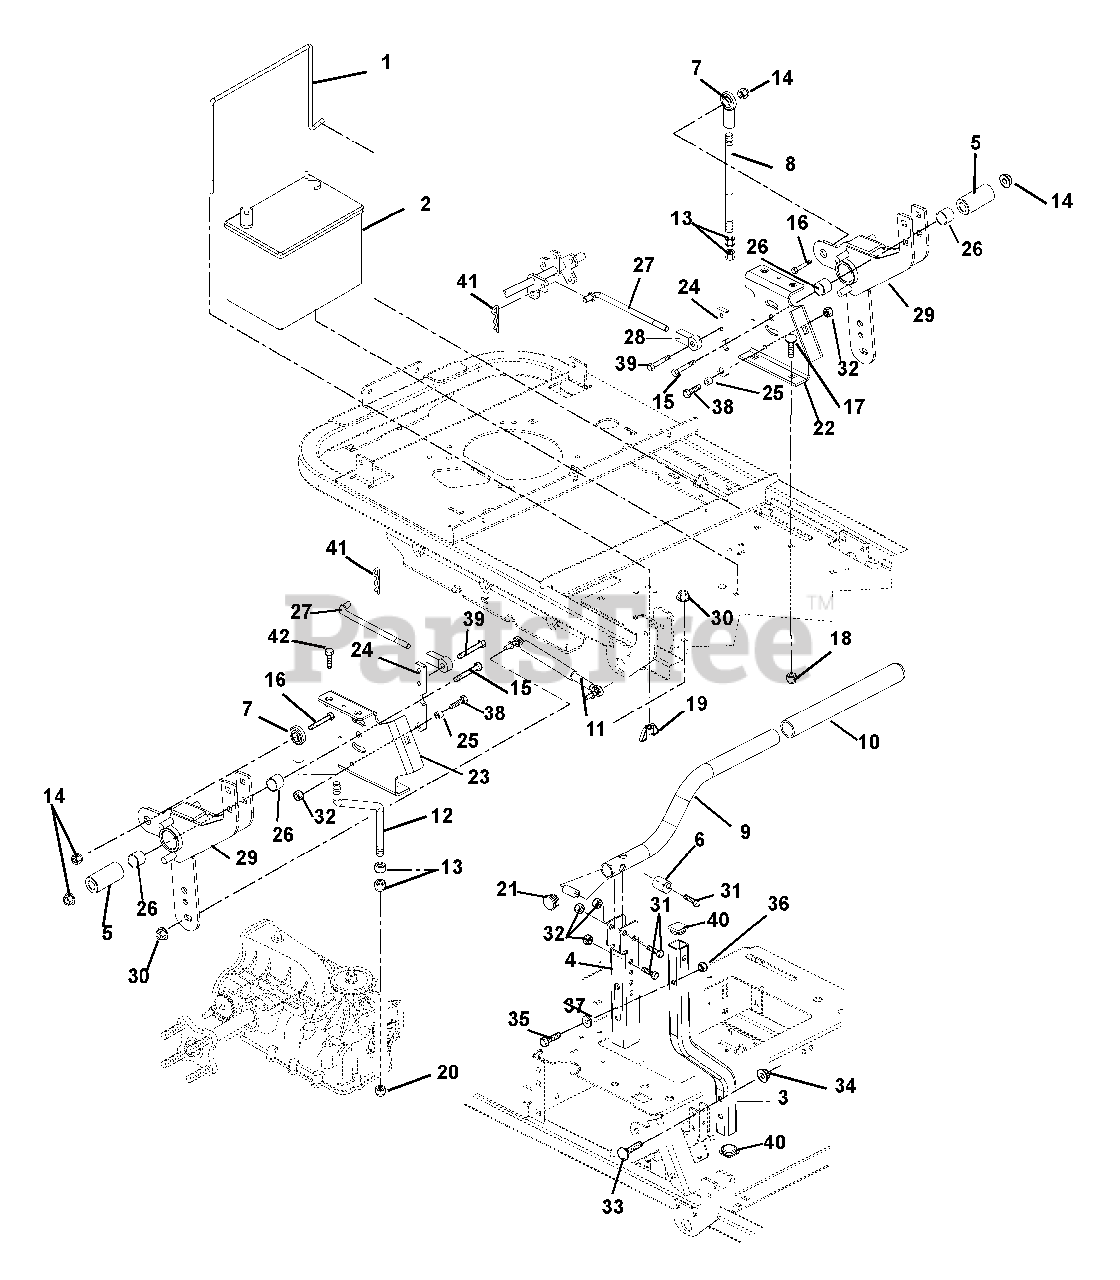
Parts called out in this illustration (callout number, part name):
1	Battery Rod
2	Battery (12 Volt, 330 CCA, 50 Min. Reserve Cap.)
3	Control Arm
4	Channel, Handlebar Adjustment
6	Eccentric
7	Rod End, .50 Right Hand
8	Rod, Transaxle Left Hand
9	Handlebar
10	Grip, Handlebar
12	Rod, Transaxle Right Hand
13	Nut, Jam .50-20 Grade 2
14	Nut, Locking Top Flange .50-13
15	Bolt, Hex .50-13 x 3.00 Grade 5
16	Bolt, Hex .50-13 x 1.75 Grade 5
17	Bolt, Round Head Square Neck .38-16 x 1.00 Grade 5
18	Nut .38-16 Flange Nyloc
19	Nut, Locking Wing .25-20
20	Nut, Jam Nyloc .50-20 Grade 2
21	Caplug, Handlebar
22	Weldment, Control LH
23	Weldment, Control RH
24	Bracket, Neutral Stop
25	Spacer, Neutral Stop
26	Bearing, 1.00 x 1.12 x .75
27	Link, Brake Rod
28	Rod, End .38 RH
29	Weldment, Steering Control
30	Nut, Locking Top Flange 8 x 1.25
31	Bolt, Hex .31-18 x 1.75 Grade 5
32	Nut, 5/16-18 Flange Nyloc
33	Bolt, Round Head Square Neck .31-18 x 1.75 Grade 5
34	Nut, Locking Top Flange .31-18
35	Bolt, Hex .25-20 x 1.75 Grade 5
36	Nut, Locking Nylon .250-20
37	Bushing, Flange .265 x .437 x .250 x .750
38	Bolt, Hex .31-18 x 1.25 Grade 5
39	Bolt, Hex .38-16 x .75 Grade 5
40	Caplug, Square
41	Pin, Hair .08 x .18 x 1.18
42	Screw, Cap .38-16 x 2
